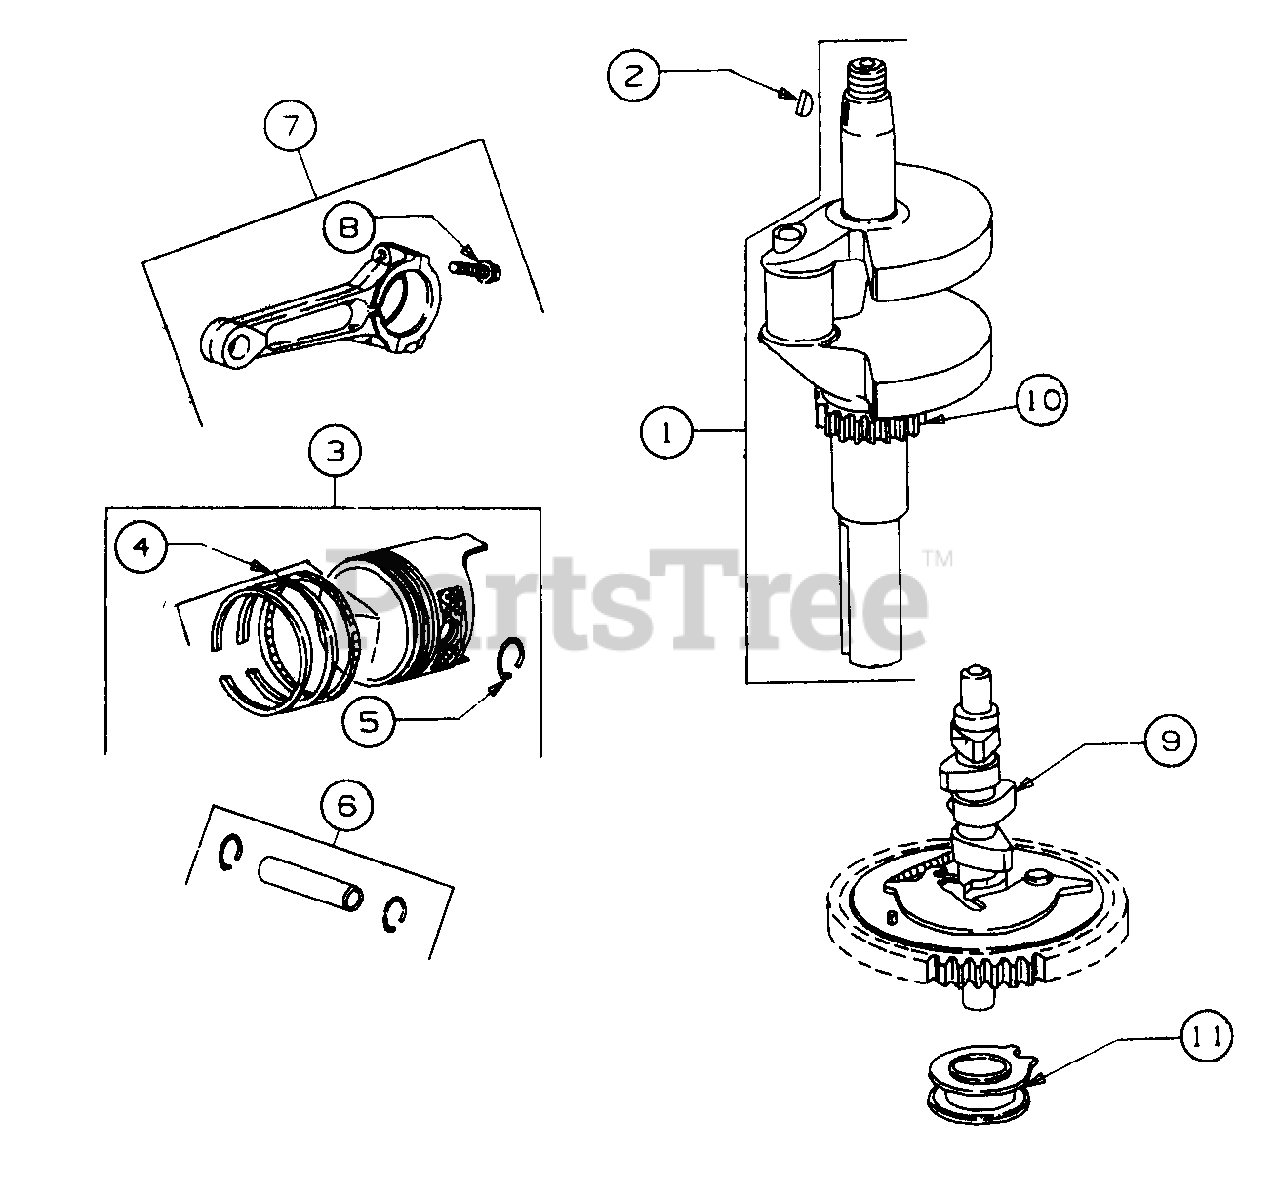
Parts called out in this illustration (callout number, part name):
1	Crankshaft
2	Key, Flywheel
3	Piston Assy (Standard)
4	Ring Set Piston (Standard)
5	Lock, Piston Pin
6	Pin Assy, Piston (Standard)
7	Rod Assy, Connecting
8	Screw, Connecting Rod
9	Gear, Cam
10	Gear, Timing
11	Slider, Governor
